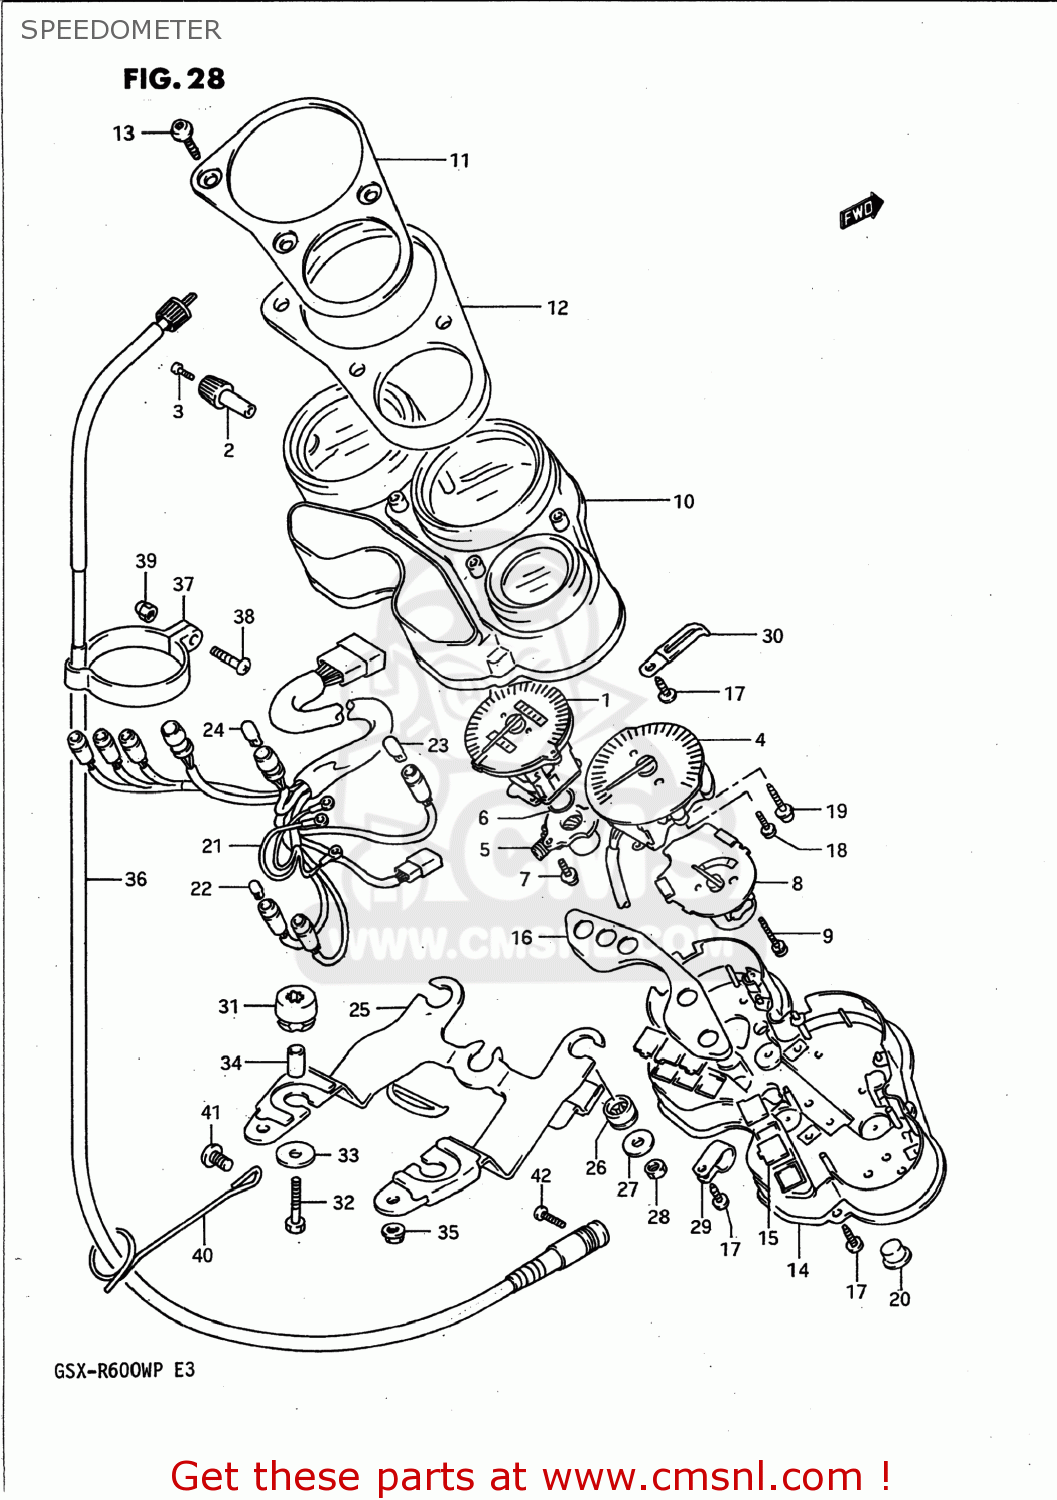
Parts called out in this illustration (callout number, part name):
1	SPEEDOMETER
2	KNOB,TRIP
3	ROTOR,SPEED
4	TACHOMETER
5	BOX,METER GEAR
6	O RING
7	SCREW
8	METER,TEMPERATURE
9	SCREW(3X22)
10	HOOD
11	PANEL,METER
12	CUSHION
13	SCREW
14	CASE,METER
15	LENS SET
16	PANEL
17	SCREW
18	SCREW
19	SCREW(4X22)
20	CAP
21	SOCKET,METER
22	BULB(12V3W,T6.5)
23	BULB(12V1.7W,T6.5)
24	BULB(12V1.7W,T10,WB121)
25	BRACKET,METER
26	CUSHION
27	SPACER,METER
28	NUT
29	CLAMP
30	CLAMP
31	GROMMET
32	BOLT
33	WASHER (6.5X20X1.6)
34	SPACER
35	NUT
36	CABLE ASSY,SPEEDOMETER
37	GUIDE,SPEEDOMETER CABLE
38	SCREW
39	NUT
40	GUIDE,SPEEDOMETER CABLE NO.3
41	SCREW
42	SCREW
